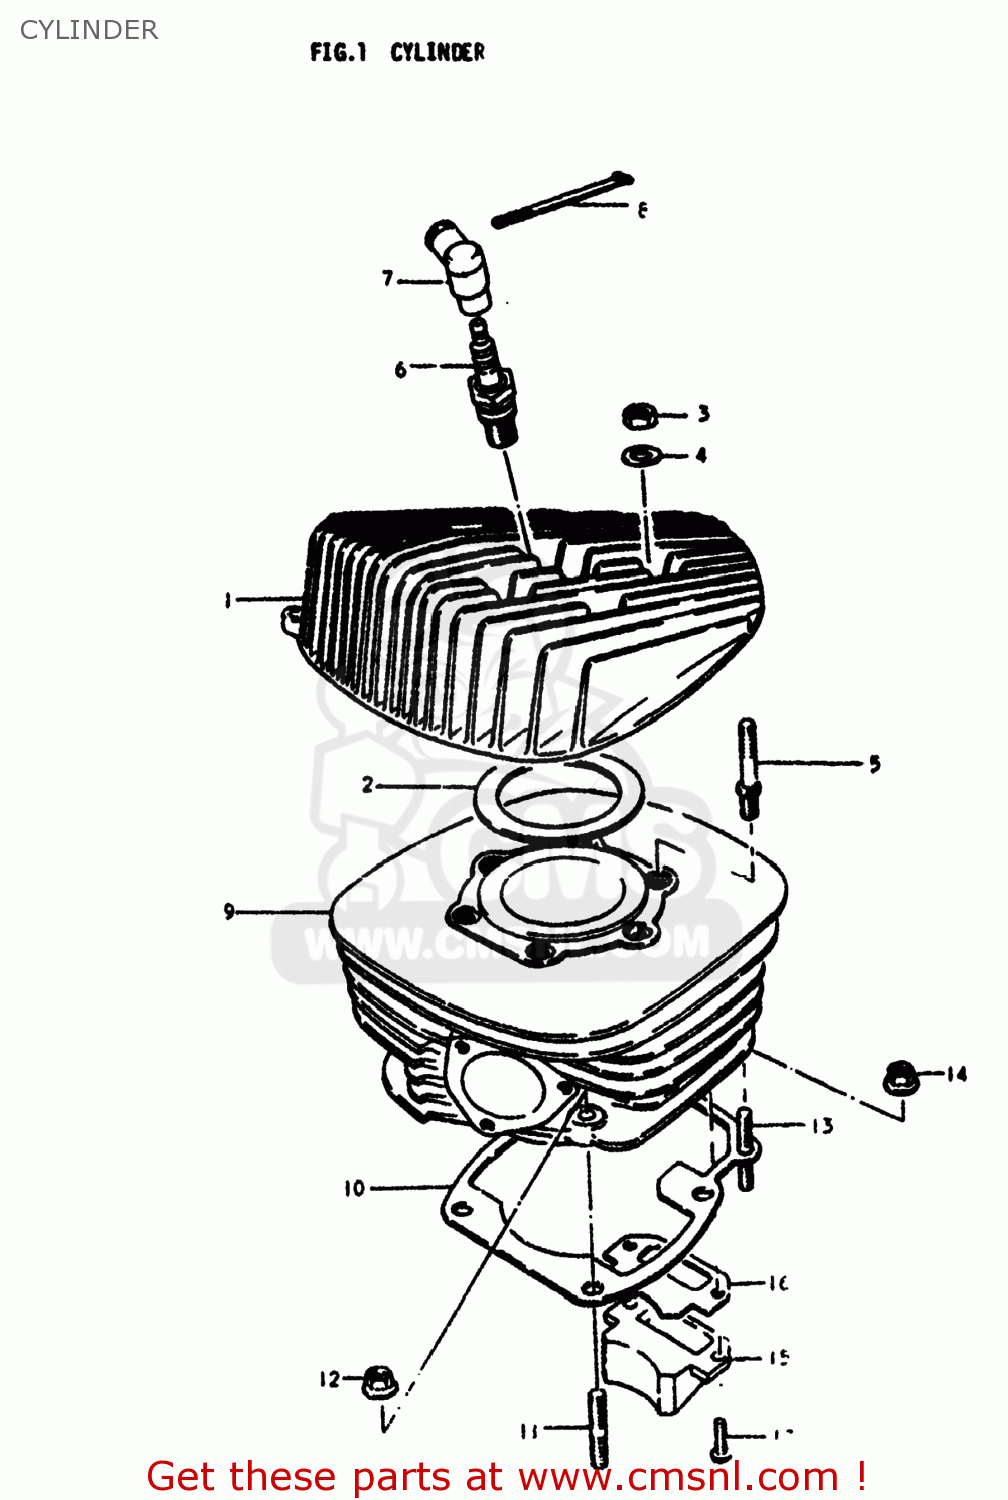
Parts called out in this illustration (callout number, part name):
1	HEAD,CYLINDER
2	GASKET,CYLINDER HEAD (NAS)
3	NUT (8MM)
4	WASHER
5	BOLT,STUD
6	SPARK PLUG
7	CAP,SPARK PLUG
8	CLAMP
9	CYLINDER
10	GASKET,CYLINDER (MCA)
11	STUD 10X30
12	NUT
13	STUD 8X25
14	NUT
15	VALVE ASSEMBLY,REED
16	GASKET,REED VALVE (MCA)
17	SCREW
